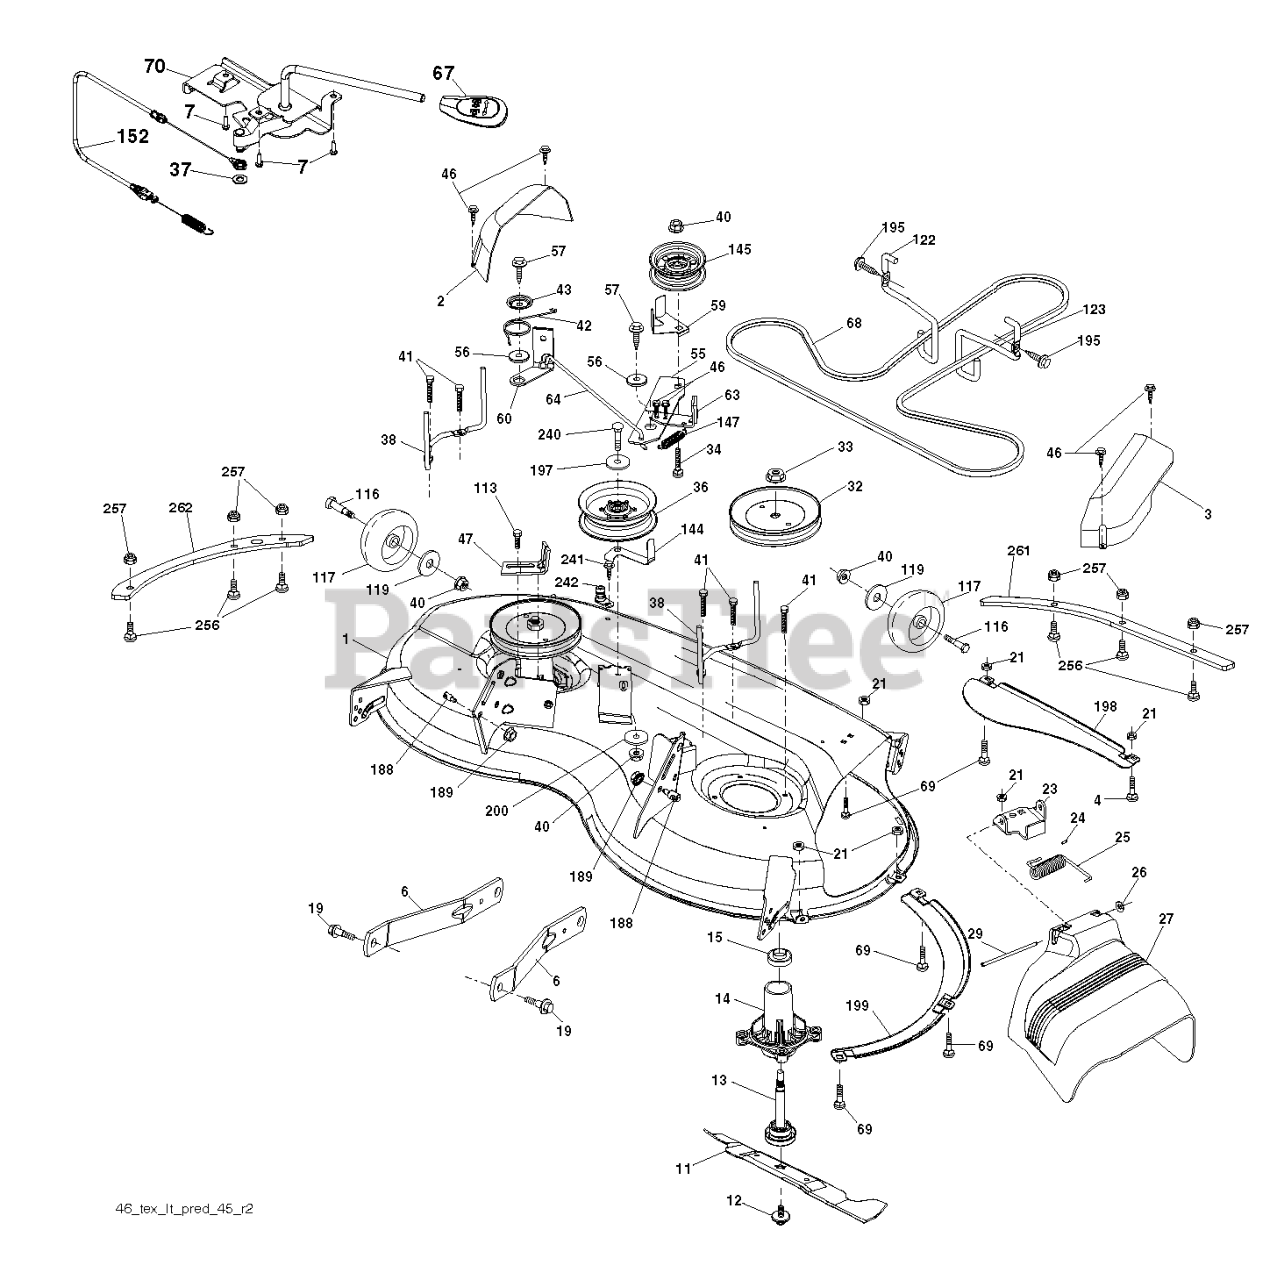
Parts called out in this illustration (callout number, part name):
1	KIT.SVC.WELDMNT.46"405050X421
2	COVER.MANDREL.LH.46"
3	COVER.MANDREL.RH.46"
4	Bolt, Hex Head 5/16-18 UNC x 3/4 (AYP part number)
6	ARM.SUSPENSION.MOWER.R
7	SCREW.#10 X 0.750.BOS (2 2)
11	BLADE.MOWER.46".HI.LIFT
12	SCREW.SEMS.7/16-20X1.HEX.HEAD
13	SHAFT ASM.MNDRL.N/GREASEABLE
14	HOUSING.MANDREL.4PT.
15	BEARING.MANDREL.TOP.EXTENDED
19	BOLT.SHOULDER
21	Locknut, Hex w/Insert 5/16-18 Unc
23	BRKT.DEFLECTOR.38"2005+
24	Cap Sleeve 80x 112 Blk Mower (AYP part number)
25	SPRING.TORSION.DEFLECT
26	Nut Push Phos & Oil (AYP part number)
27	SHIELD.DEFLECTOR.MOWER.46"BLAC
29	Rod Hinge 42" 6 75 Wlg (AYP part number)
32	PULLEY.MANDREL.5.438.PD
33	NUT.FLANGE.LOCK.TOP
34	Bolt Carriage 3/8-16 x 1-1/2 (AYP part number)
36	PULLEY.IDLER.2006
37	Washer 13/32 x 1-3/16 x 12 Gauge (AYP part number)
38	KEEPER.BELT.MANDREL.PULLEY
40	NUT LOCK FLG 3/8-16 UNC
41	BOLT.HEX.WASHR.HED.313-18X1.19
42	SPRING.TORSION.BRAKE
43	SRPING.TORSION.RETAINE
46	Screw Hex Thd Cut 1/4-20x5/8 T (AYP part number)
47	BRKT.CLUTCH.CABLE
55	IDLER.ARM
56	SPACER.RETAINER
57	SCREW 3/8-16X1
59	Guard TUV Idler (AYP part number)
60	ARM BRAKE MOWER RH 38"
63	ARM BRAKE MOWER
64	LINKAGE BRAKE
67	HANDLE.CLUTCH.CABLE.LT
68	V-BELT
69	Bolt, Carriage 5/16-18 UNC x 5/8 (AYP part number)
70	CLUTCH.ASM.MANUAL.YT.PREDATORQ
113	BOLT.5/16HEX.WHS.HD
116	Bolt, Shoulder (AYP part number)
117	WHEEL.GAUGE.RALLY.NARROW
119	Washer 3/8 x 7/8 x 14 Ga. (AYP part number)
122	KEEPER BELT ENGINE LH
123	KEEPER BELT RH
144	KEEPER.BELT.MOWER
145	PULLEY.IDLER.48"PRIMARY
147	RETURN SPRING
152	CABLE.MECHANICAL.CLUTCH
188	STUD.FASTNER.W/ANTI-ROTATE
189	NUT LOCK HEX FLANGE 5/16-18
195	SCREW, 3/8-16X3/4
197	Washer 13/32 x 13/16 x 12 Gauge (AYP part number)
198	BAFFLE CENTER FRONT
199	BAFFLE FRONT RH
200	WASHER.13/32 X 1 X 1/2.11GUARD
240	BOLT-HEX EAK
241	SCREW.TT.#10-32X.5.3/8.FLANGE
242	PORT.WASHOUT
256	RHSNB, 1/4-20 X 1, GR5
257	Nut, Hex Flange 1/4-20
261	PLATE.REINF.DECK.46".FRONT.BLK
262	PLATE.REINF.DECK.46".SIDE.BLK
